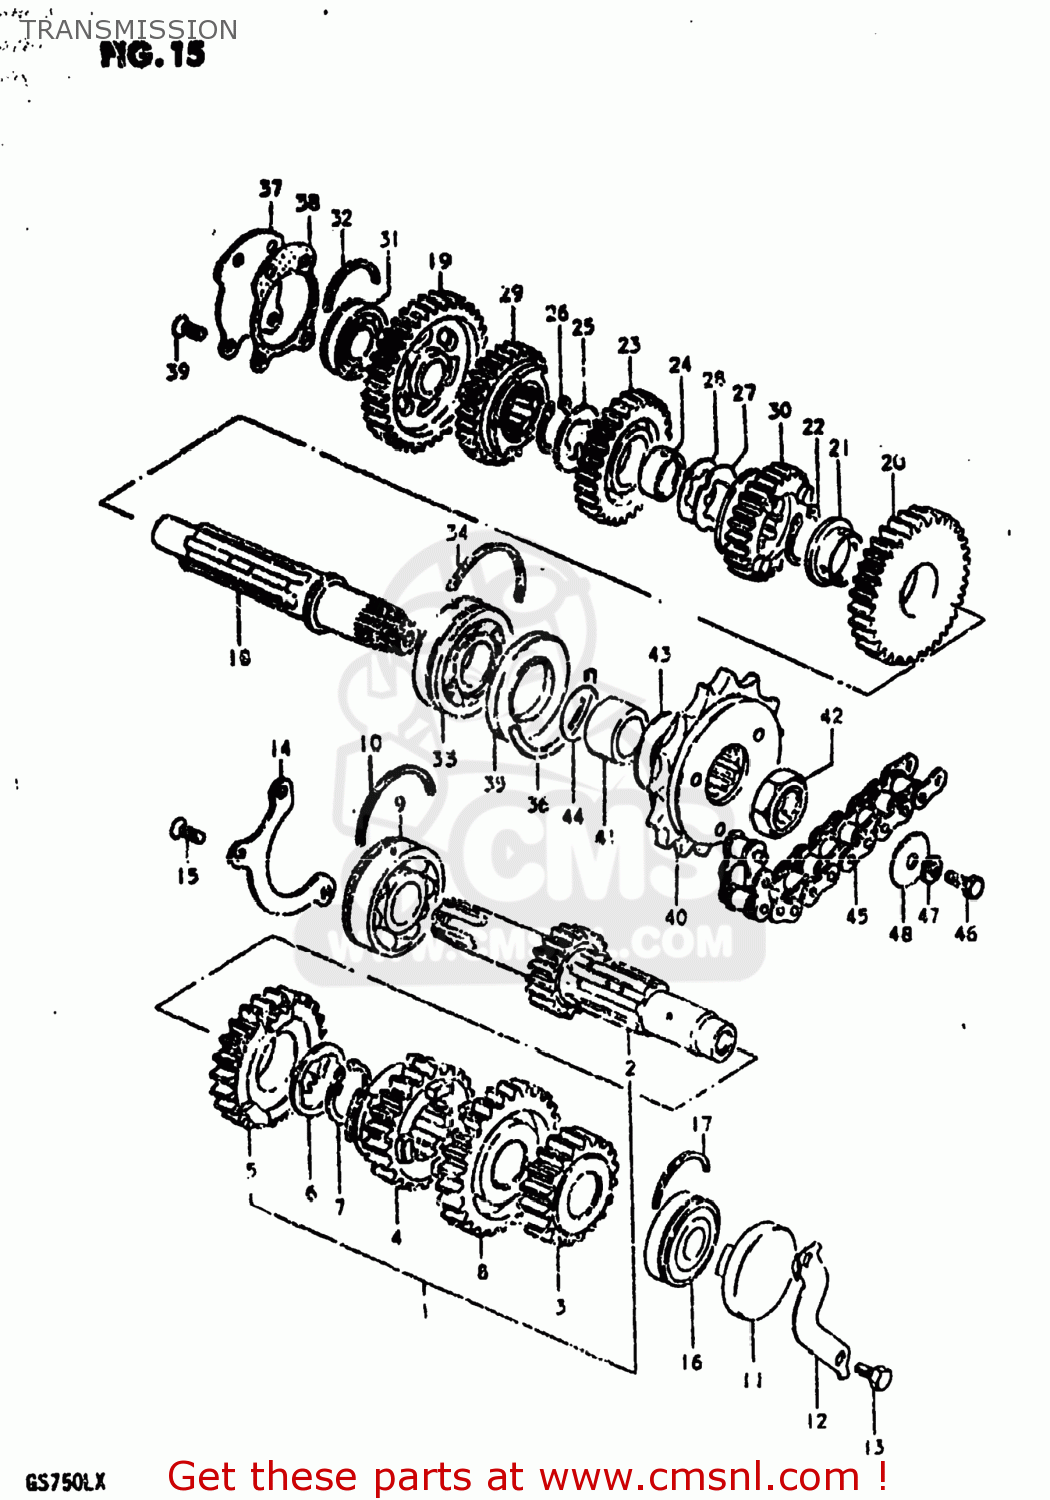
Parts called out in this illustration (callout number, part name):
1	SHAFT ASSEMBLY,COUNTER
2	SHAFT,COUNTER
3	GEAR,SECOND DRIVE
4	GEAR,THIRD DRIVE
5	GEAR,FOURTH DRIVE
6	WASHER,LOCK
7	CIRCLIP
8	GEAR,FIFTH DRIVE
9	BEARING(25X62X17)
10	C-RING
11	PLUG
12	RETAINER,CL PUSH ROD OIL SEAL
13	BOLT
14	RETAINER,CNTR SHAFT BEARING
15	SCREW
16	BEARING(20X47X14)
17	C RING
18	SHAFT,DRIVE
19	GEAR,FIRST DRIVEN
20	GEAR,SECOND DRIVEN
21	BUSH(28X32X2)
22	CIRCLIP
23	GEAR,THIRD DRIVEN
24	BUSH,3RD DRIVEN GEAR
25	WASHER,LOCK
26	CIRCLIP
27	WASHER,LOCK
28	WASHER
29	GEAR,FOURTH DRIVEN
30	GEAR,FIFTH DRIVEN
31	BEARING
32	C RING
33	BEARING(25X62X17)
34	C-RING
35	SEAL,OIL(32X62X7)
36	C RING
37	PLATE,DRIVE SHAFT
38	GASKET,DRIVESHAFT PLATE (MCA)
39	SCREW
40	SPROCKET,ENGINE
41	SPACER(25X32X18.6)
42	NUT
43	WASHER
44	O RING(D:1,ID:24.5)
45	CHAIN ASSEMBLY,DRIVE
46	BOLT, UPPER
47	LOCK WASHER
48	WASHER
